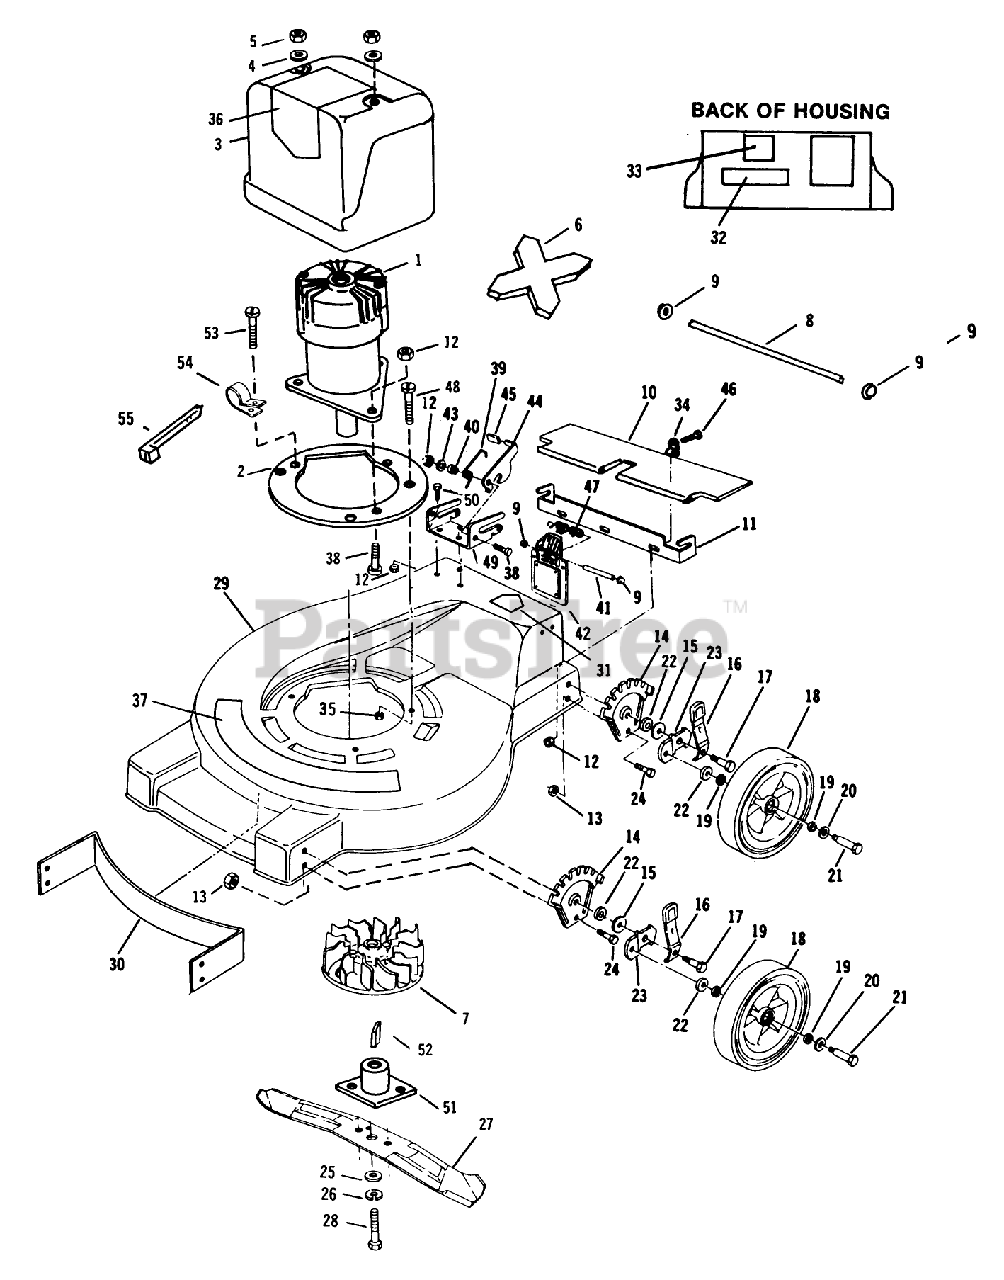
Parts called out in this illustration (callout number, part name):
1	Motor
3	Shroud
4	Washer
5	Nut
6	Filter
7	Fan
10	T/SHIELD SM&P
12	LOCKNUT E
13	LOCKNUT
15	WASHER
16	KNOB & SPRING
17	BOLT
19	WASHER
20	SPACER
21	BOLT WHEEL
22	WASHER WROUGHT
26	LOCKWASHER
35	NUT-LOCK F
39	SPRING
41	ROD ROCK/HDWE
47	SPRING ASOC
48	SCREW
53	SCREW F
